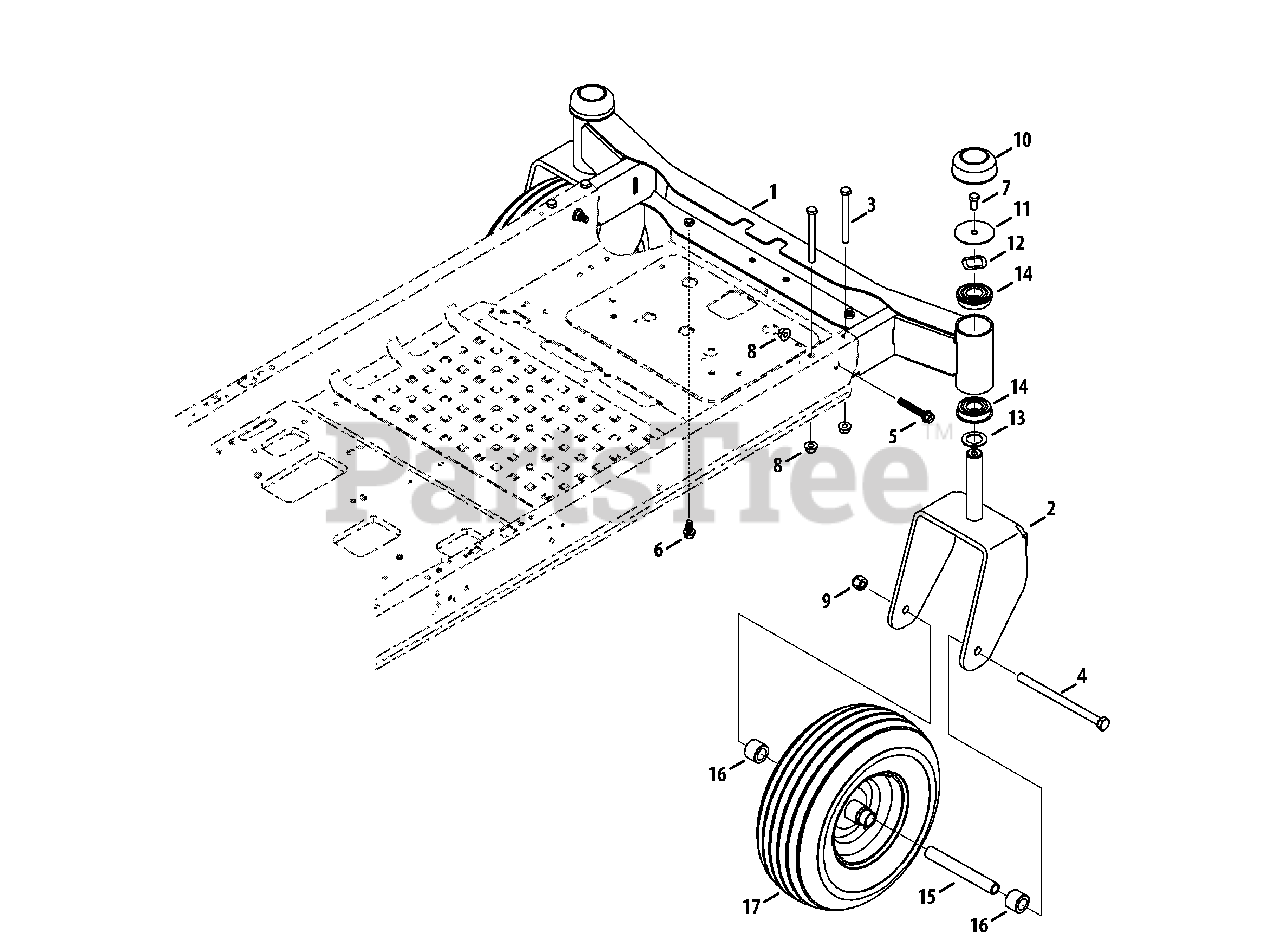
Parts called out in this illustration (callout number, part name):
1	Front Axle
2	Caster Wheel Bracket
3	Hex Cap Screw, 3/8-16 x 3.75
4	Hex cap Screw, 1/2-20 x 7.25
5	Hex Flange Screw, 3/8-16 x 2.25
6	Screw TT, 3/8-16 x .750
7	Hex Cap Screw, 3/8-16 x .750
8	Flange Lock Nut, 3/8-16
9	Hex Lock Nut, 1/2-20
11	Flat Washer, .406 x 2.50 x .060
12	Wave Washer, 1.25 x 1.00 x .300
13	Flat Washer, 1.010 x 1.56 x .060
14	Ball Bearing
15	Spacer, .51 x .75 x 5.825
16	Hub, .76 x 1.23 x .92
17	Wheel Assembly, 13 x 5-6, CARLISLE TIRE
17	Wheel Assembly, 13 x 5-6, DELI TIRE
